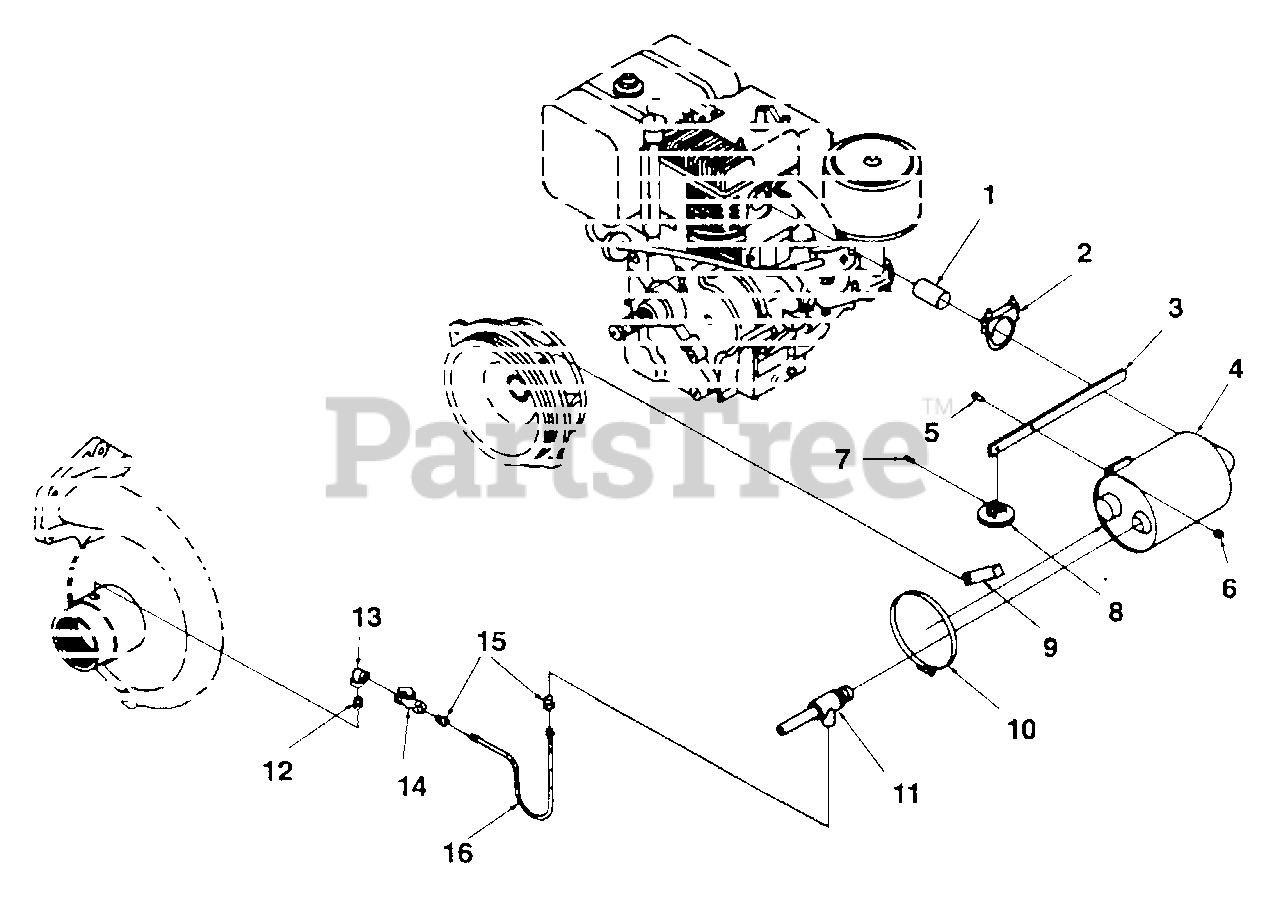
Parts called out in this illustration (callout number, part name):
1	NIPPLE - Pipe
2	CLAMP - Muffler
3	LEVER - Prime
4	MUFFLER
5	SCREW - Hex Hd. (1/2-20 x 3/4)
6	NUT - Locking Hex
7	PIN - Spirol
8	VALVE - Flapper
9	BRACE - Muffler
10	STRAP - Muffler
11	VENTURI - Priming
12	NIPPLE - Close (1/4")
13	FITTING - Street
15	CONNECTOR 45ø flare
16	LINE - Vacuum
